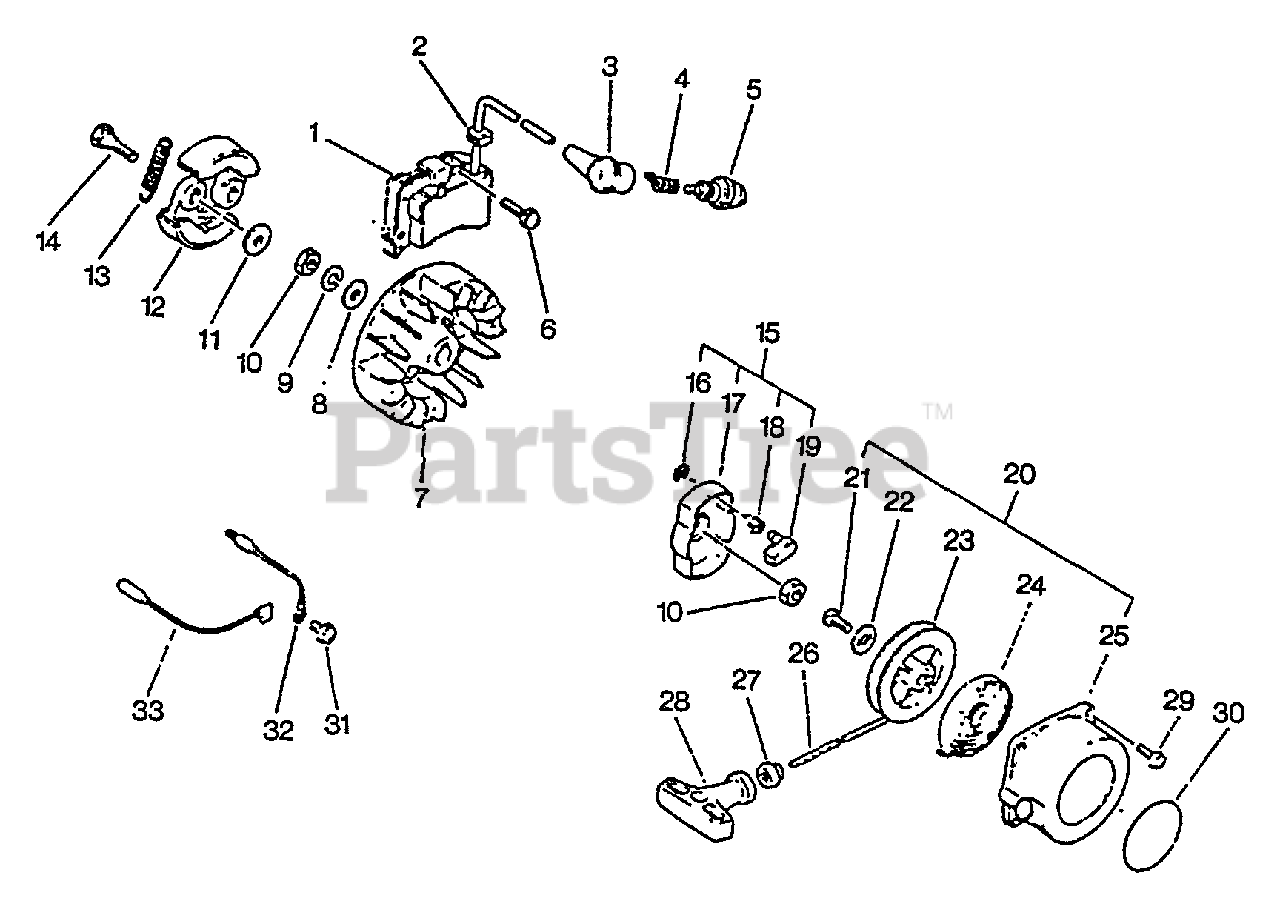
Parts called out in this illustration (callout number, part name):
1	COIL, IGNITION
3	CAP, SPARK PLUG
4	TERMINAL, SPARK PLUG
5	SPARK PLUG - BPM7A
5	SPARK PLUG - BPMR7A
6	SCREW 5×20
7	FLYWHEEL
8	WASHER 8.5×16×1.2
9	WASHER, SPRING 8
10	NUT 8×1.25
11	WASHER 6.2×19×1.0
12	SHOE, CLUTCH
13	SPRING, CLUTCH
14	BOLT, CLUTCH
15	PAWL ASSY, STARTER
16	RING, RETAINING - 6
17	CATCHER, PAWL
18	SPRING, RETURN
19	PAWL, STARTER
20	STARTER ASSY
22	WASHER
23	REEL, ROPE
24	SPRING, RECOIL
25	CASE, STARTER
26	ROPE, STARTER 3.5×850
27	GUIDE, ROPE
28	GRIP, STARTER
29	SCREW 4×14
30	LABEL, ECHO
31	SCREW 5×10
32	LEAD - GROUND L= 115
33	LEAD - GROUND
